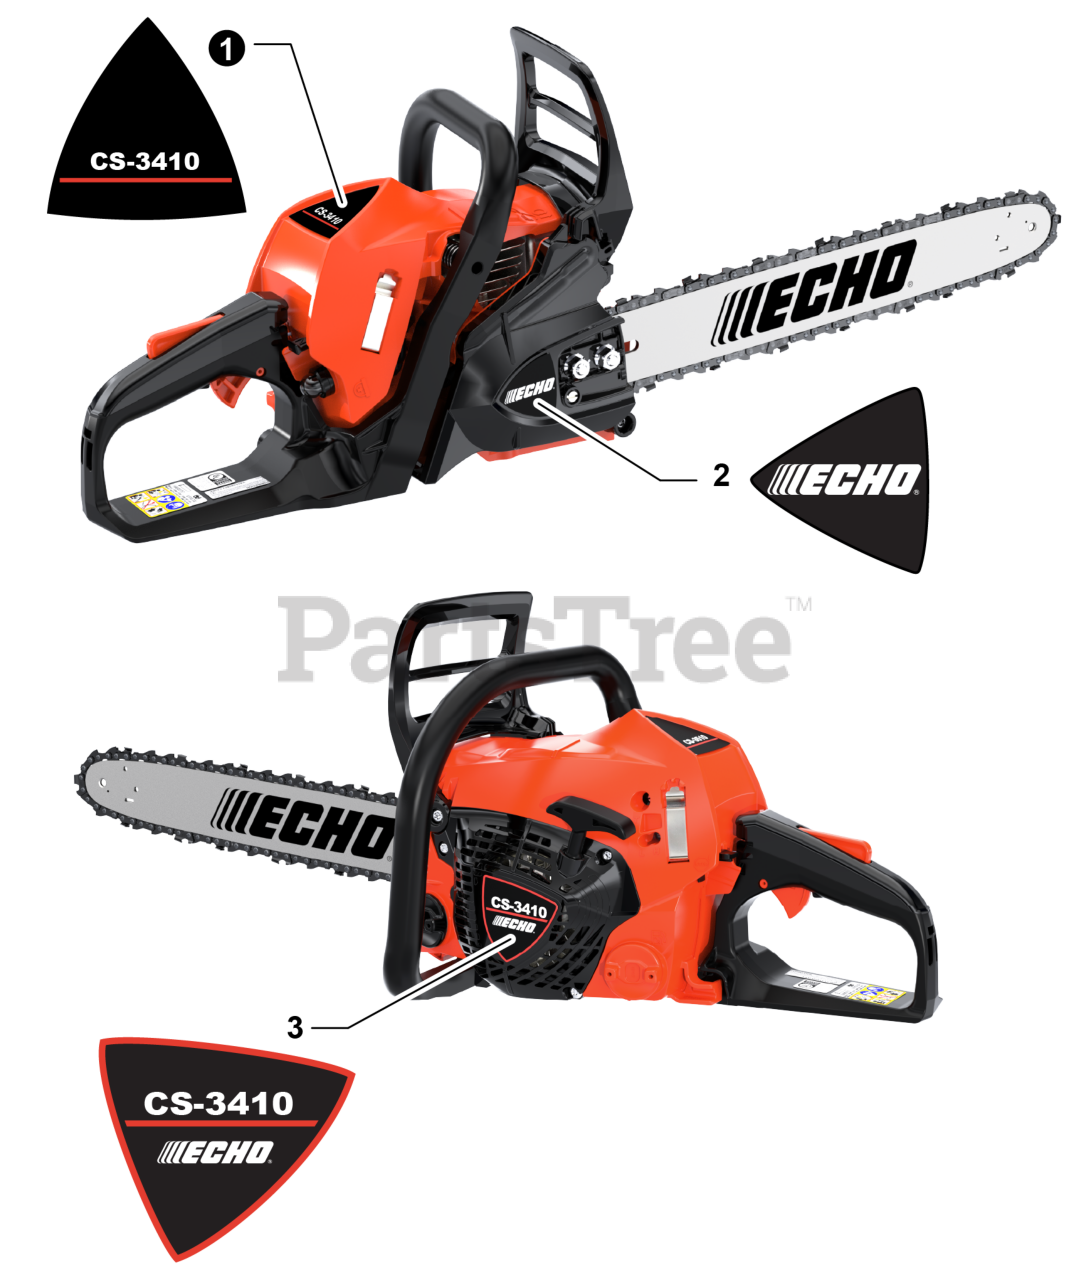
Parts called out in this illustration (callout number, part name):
1	LABEL - MODEL CS-3410
2	LABEL - ECHO
3	LABEL - RECOIL STARTER
